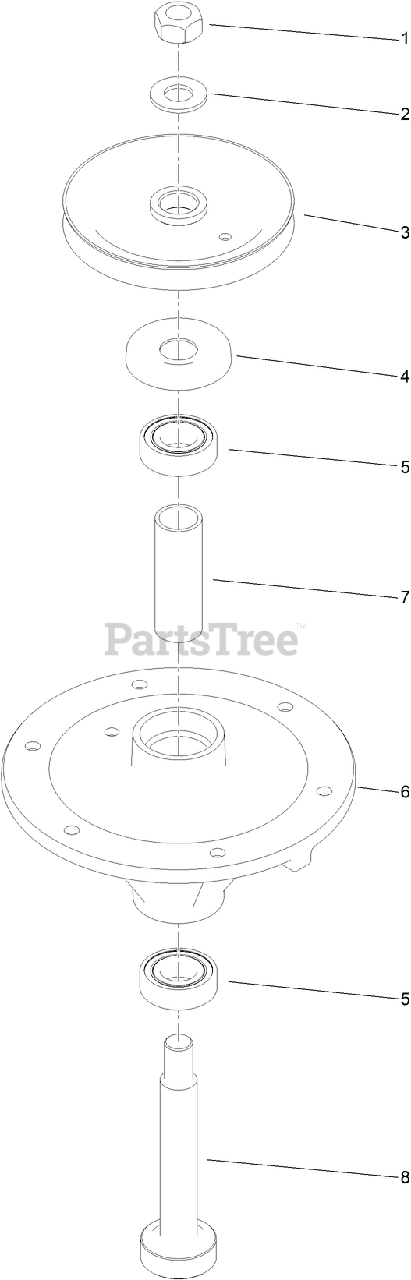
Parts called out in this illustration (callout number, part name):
1	NUT-HEX
2	WASHER
3	PULLEY
4	SHIELD-BEARING
5	BEARING-BALL
6	HOUSING-SPINDLE
7	SPACER-BEARING
8	SHAFT-SPINDLE
